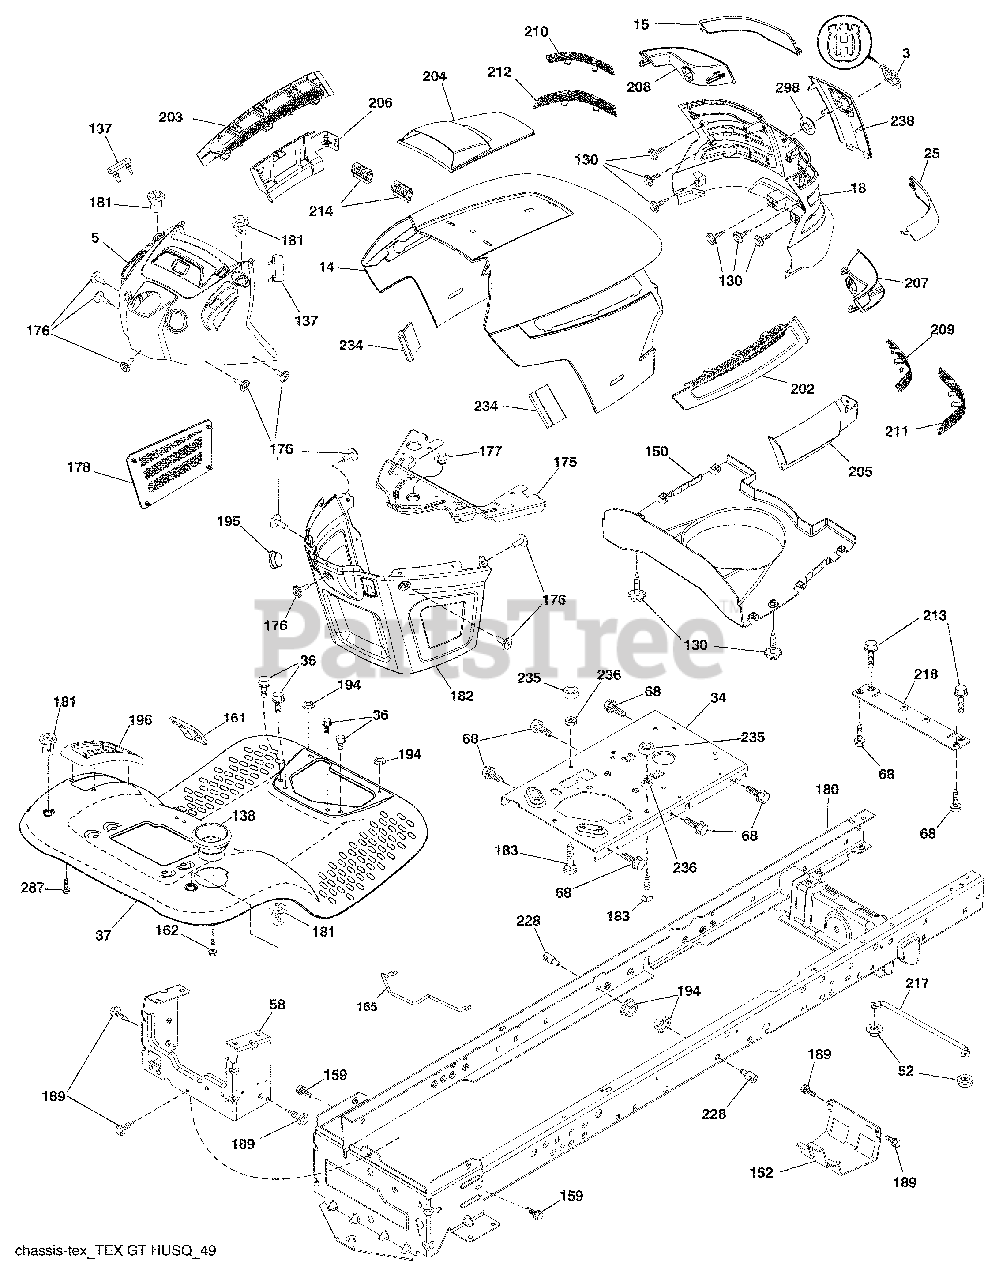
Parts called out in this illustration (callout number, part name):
3	Logo
5	Dash Asm. Husq.
14	Hood
18	Grille Asm.
26	Spring Return Cruise
34	Plate Engine
36	Screw 5/16-18 x 3/4
52	Nut Lock 5/16-18
58	Drawbar Upper
68	Screw Thdrol 5/16-18 x 1/2
130	Screw #10 x 0.750
137	Bumper Dash
138	Cupholder
152	Shield Browning
159	Screw 3/8-16 x 3/4
161	Window Fuel
165	Support Tank Rear
175	Crossmember
176	Screw 10-24 x 5/8
177	Bushing Steering
178	Cargo Net Asm.
181	Bushing Mtg. Fender Crgo
182	Dash Lower
183	Bolt Fin Hex 5/16-18 unc x 1-1/4
189	Screw 5/16-18 x 3/4
194	Nut Lock Hex Flange 5/16-18
195	Plug Hole Dash Lower
196	Console Asm. Deck Lift
202	Vent Side Hood RH
203	Vent Side Hood LH
204	Vent Top Hood
205	Skirt Hood Side RH
206	Skirt Hood Side LH
209	Insert Hex Top RH
210	Insert Hex Top LH
211	Insert Hex Bottom RH
212	Insert Hex Bottom LH
213	Bolt 5/16-18 x 3/4
214	Clip Retainer Tinner
218	X-Piece Hood Stop
228	Stud Fastner
234	Bumper Hood
235	Spacer Fender
236	Nut Lock 5/16-18 unc
287	Screw 1/4-20 x 3/8
